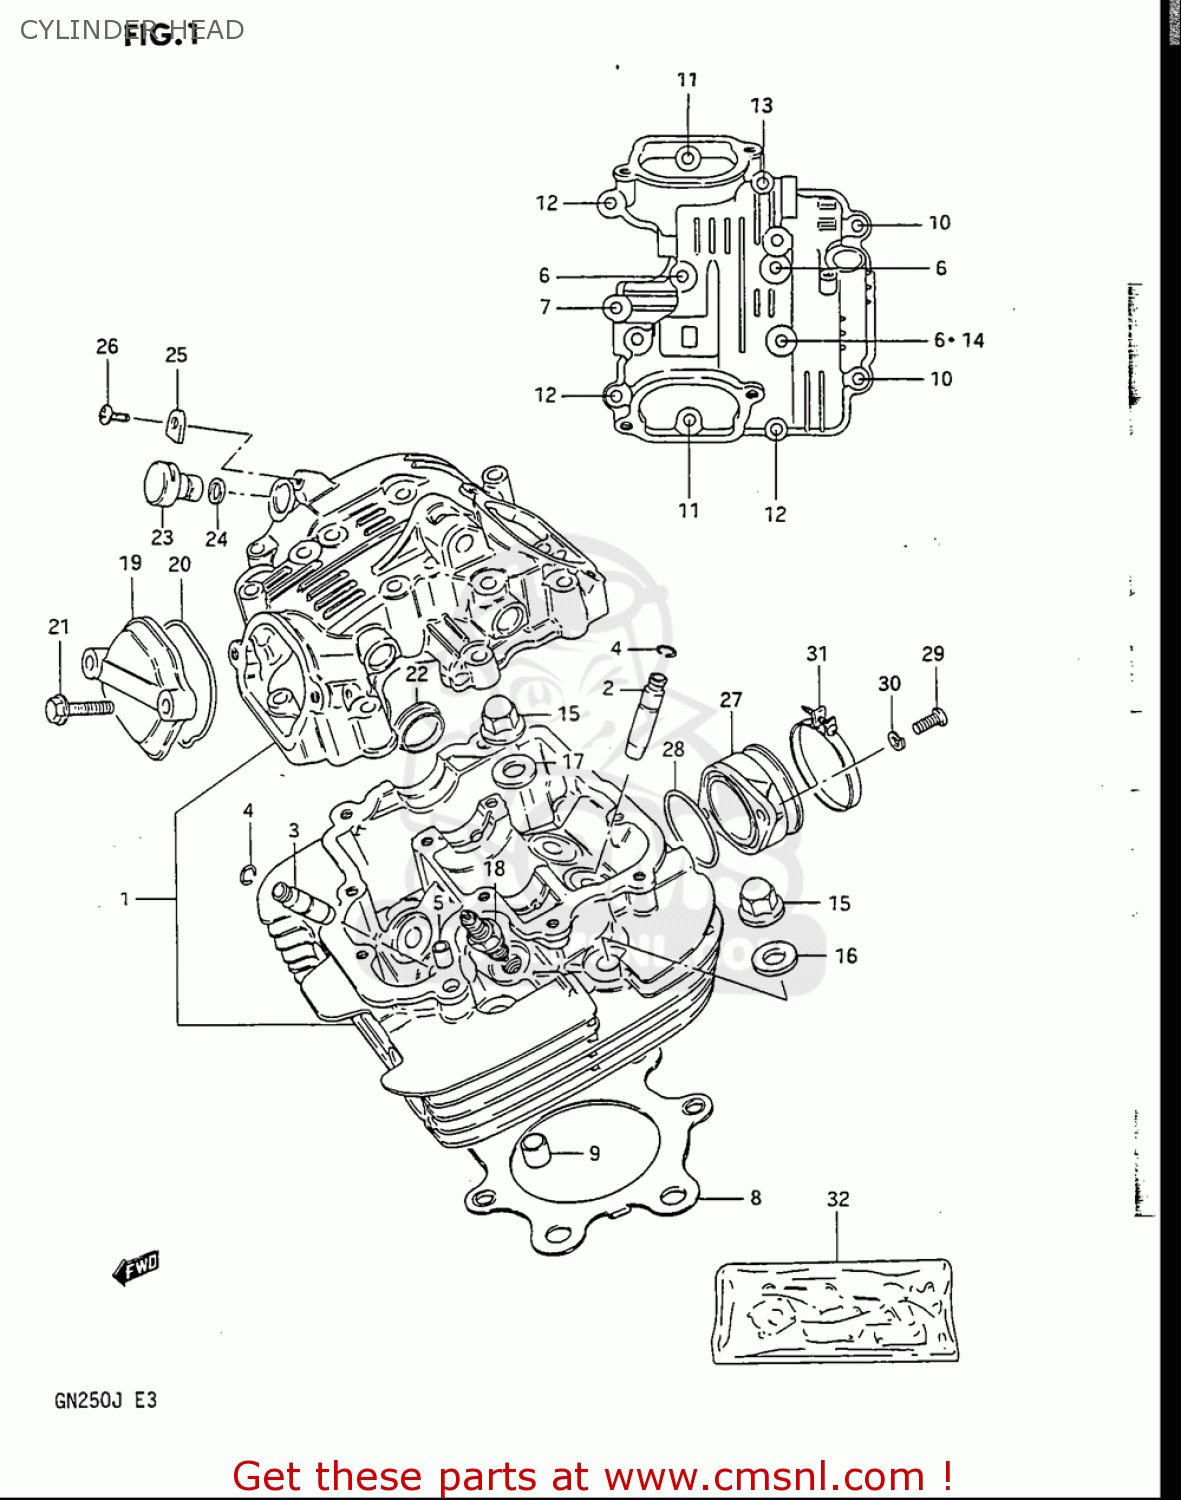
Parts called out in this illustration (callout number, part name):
1	HEAD ASSY,CYLINDER
2	GUIDE,INTAKE VALVE
3	GUIDE,VALVE
4	RING,SNAP
5	PIN(6.2X8X11)
6	BOLT
7	BOLT
8	GASKET,CYLINDER HEAD (NAS)
9	PIN
10	BOLT(6X115)
11	BOLT
12	BOLT
13	BOLT
14	GASKET(5.8X13X1.2) (NAS)
15	NUT
16	WASHER(10.5X22X2.3)
17	GASKET(10.5X22X2) (NAS)
18	SPARK PLUG D8EA
19	CAP,INSPECTION
20	O RING(D:2.4,ID:23)
21	BOLT
22	PLUG(OD:30)
23	PLUG,TACH GEAR SLEEVE HOLE
24	SEAL,TACHOMETER DRIVEN
25	PLATE,TACH DRIVE GEAR SLEEVE
26	SCREW(5X12)
27	PIPE,INTAKE
28	O RING(D:2.4,ID:39.7)
29	SCREW
30	WASHER,LOCK
31	CLAMP
32	GASKET SET
